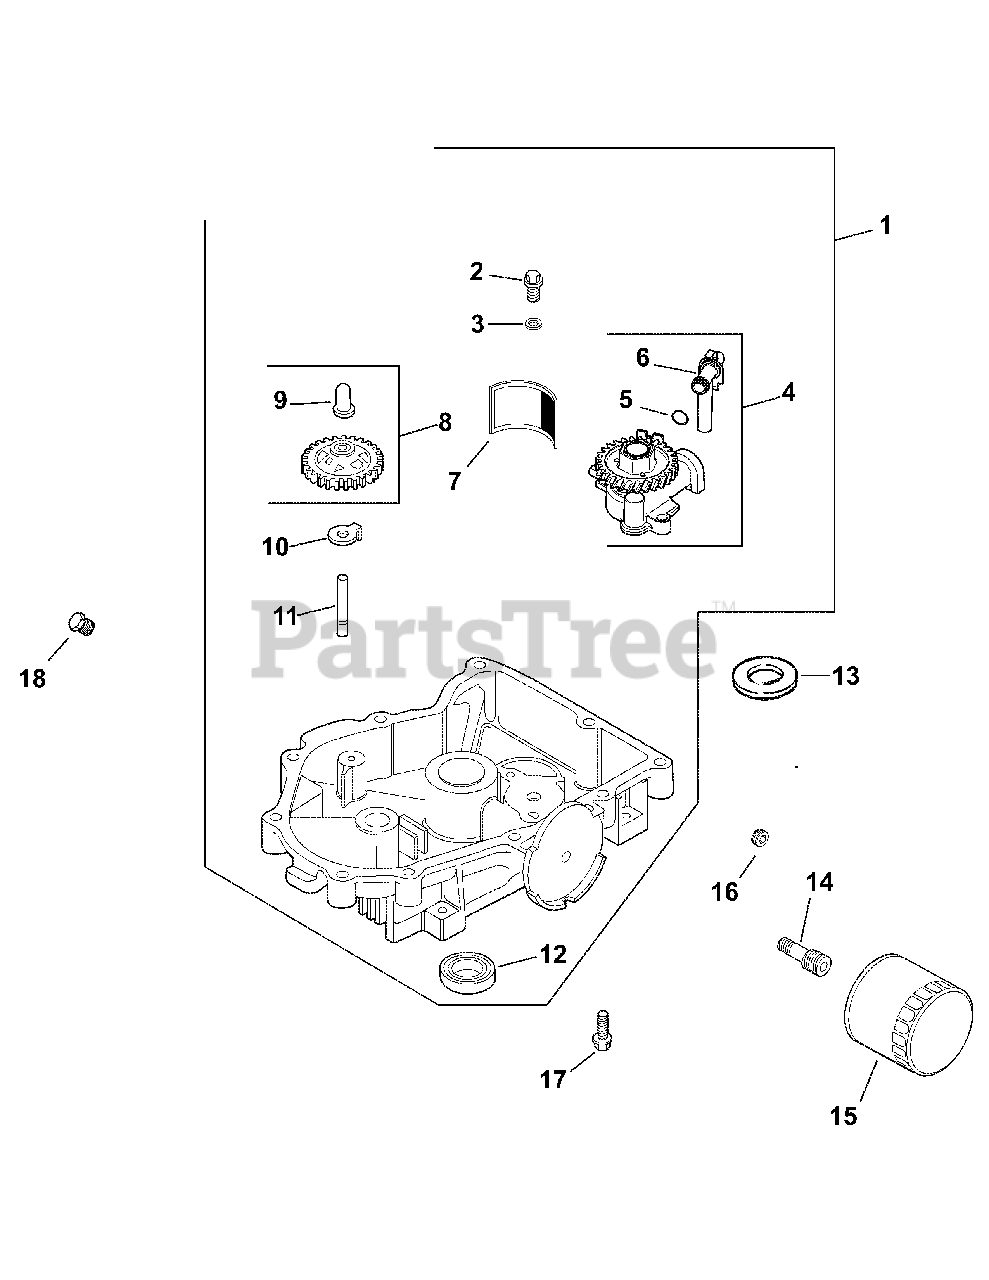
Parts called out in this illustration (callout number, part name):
1	Pan, Oil Assembly
2	Screw, SHD THD FRM M6 x 1.0 x 25
3	Washer, Flat 6MM
4	Kit, Oil Pump Assembly
5	O-Ring, Oil Pick-Up
6	Tube, Oil Pick Up
8	Kit, Governor Gear w/ Pin
9	Pin, Governor Regulating
11	Shaft, Governor Gear
14	Nipple, Oil Filter
16	Plug, Pipe CTSK 3/8"
17	Screw, Flg M8 x 1.25 x 45
18	Plug, Hd Pipe 3/8"
